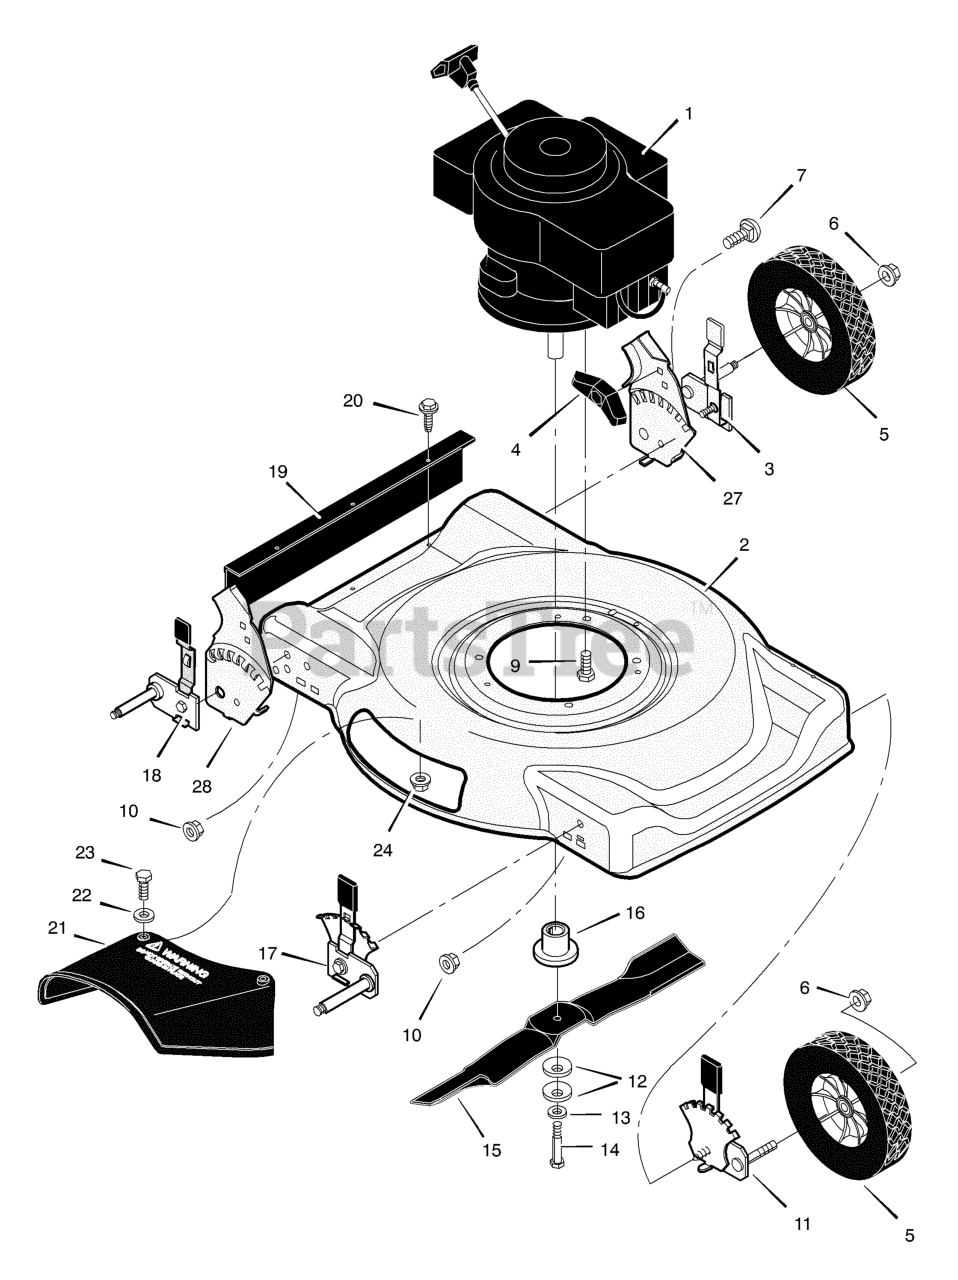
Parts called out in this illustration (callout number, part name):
1	Engine *
2	Housing
3	Height Adjuster, Left Rear
5	Wheel and Tire (White)
6	Locknut, Flange
7	Bolt, Carriage
9	Bolt, Engine
10	Nut
11	Height Adjuster, Left Front
12	Washer, Belleville
14	Bolt, Hex
15	Blade, Side Discharge
16	Adapter, Blade
17	Height Adjuster, Right Front
18	Height Adjuster, Right Rear
19	Guard, Rear
20	Screw
21	Deflector, Chute
22	Washer
23	Bolt, Hex
24	Nut, NYLOCK
27	Bracket, Left Handle
28	Bracket, Right Handle
